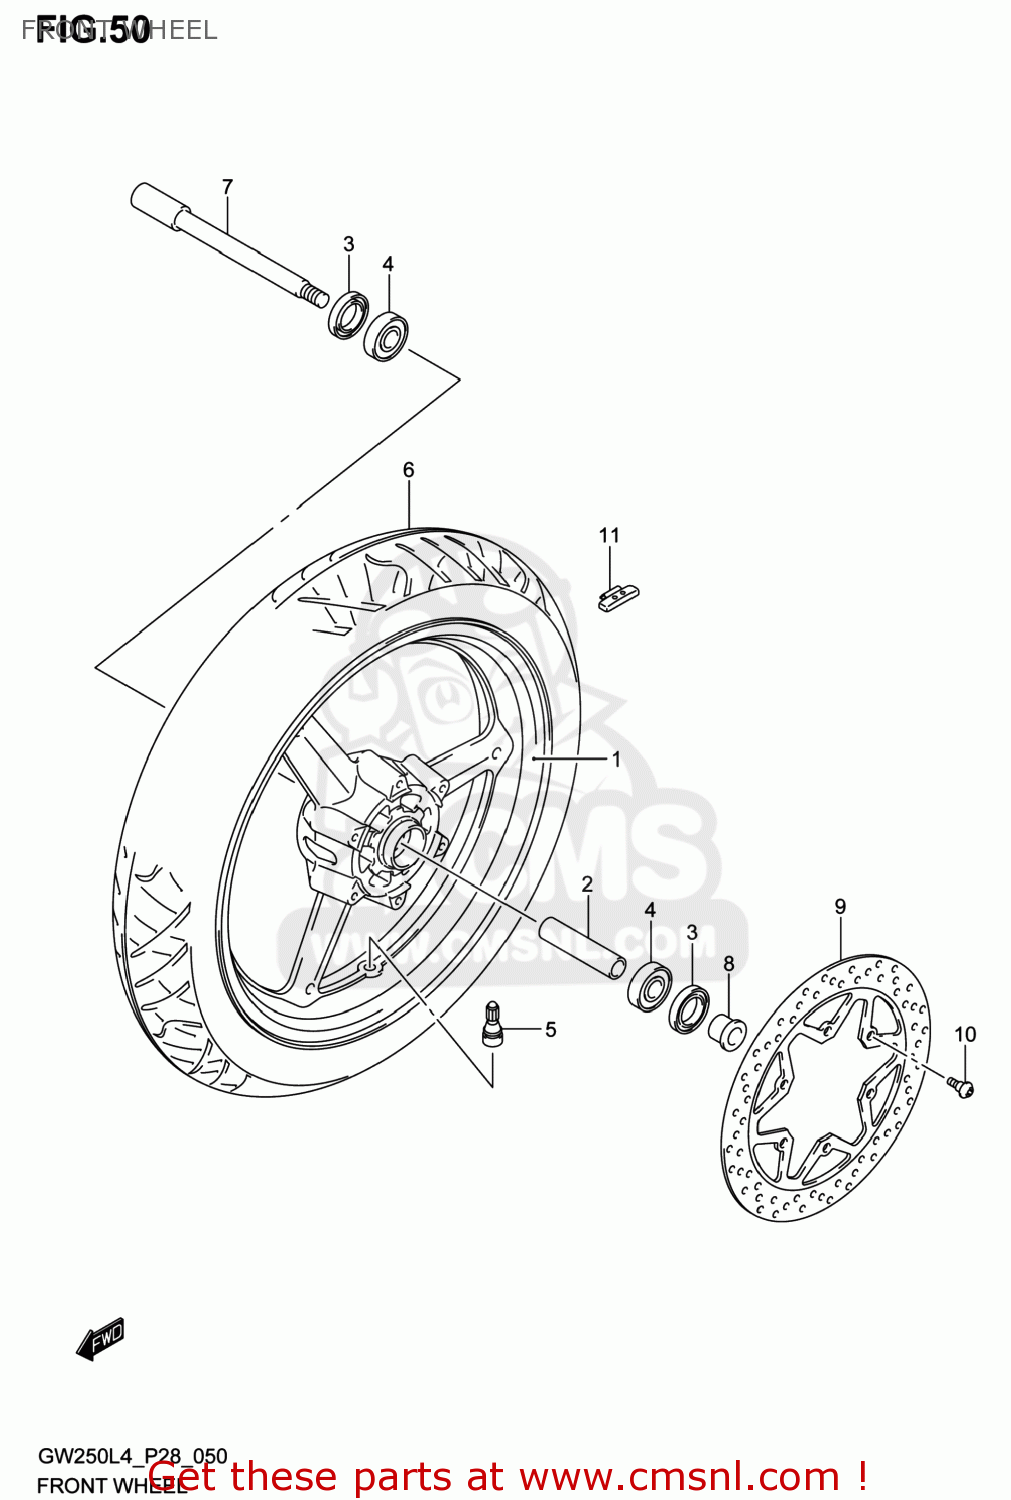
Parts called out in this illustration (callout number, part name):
1	WHEEL,FR(17M/CXMT3.00)
2	SPACER,FR HUB BEARING
3	SEAL,FR HUB
4	BEARING
5	VALVE ASSY,WHEEL RIM(TR412)
6	TIRE,FR(110/80-17M/C 57H)
7	AXLE,FRONT
8	SPACER,FR AXLE,L
9	DISC,FR BRAKE
10	BOLT,FR BRAKE DISC
11	BALANCER,WHEEL(10G)
